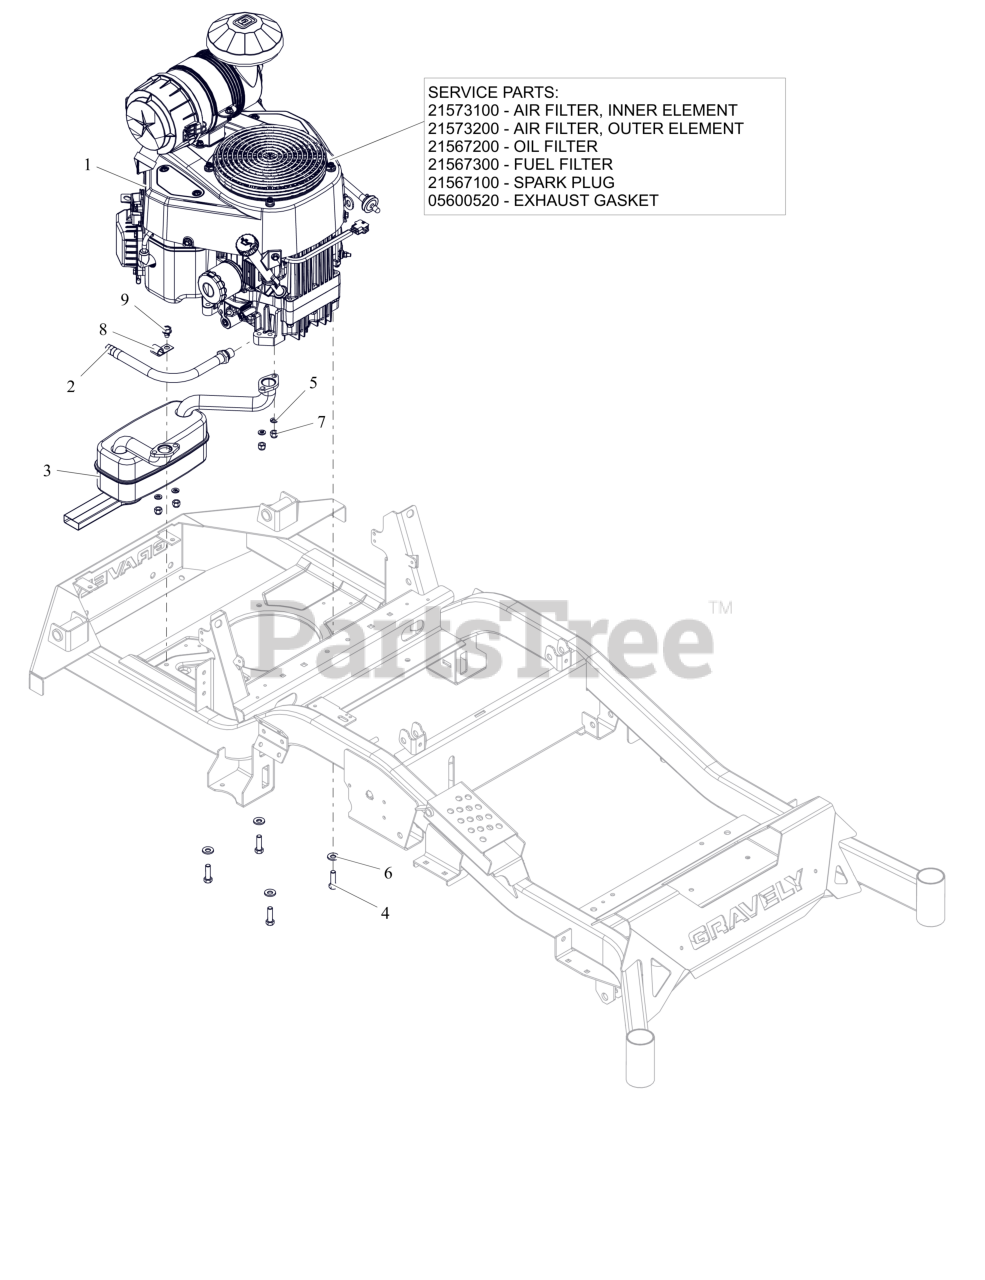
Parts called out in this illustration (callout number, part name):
1	ENGINE, GRAVELY 764CC PRO FILTER
1	FILTER, ELEMENT INNER
1	ELEMENT, AIR FILTER
1	FILTER, OIL LONCIN
1	FILTER, FUEL
1	PLUG, SPARK
1	GASKET, MUFFLER LONCIN
2	HOSE, OIL DRAIN
3	MUFFLER,
4	BLT, HEX .38-16X1.25 G5 ZCC NT
5	WSHR,LK-REG .312X.078 ZCC
6	WASHER, 3/8" SPRING DISC
7	NUT,NYL M8-1.25 G8.8 ZCC
9	SCR,TAP .375-16X.50 HWH TR ZCC
